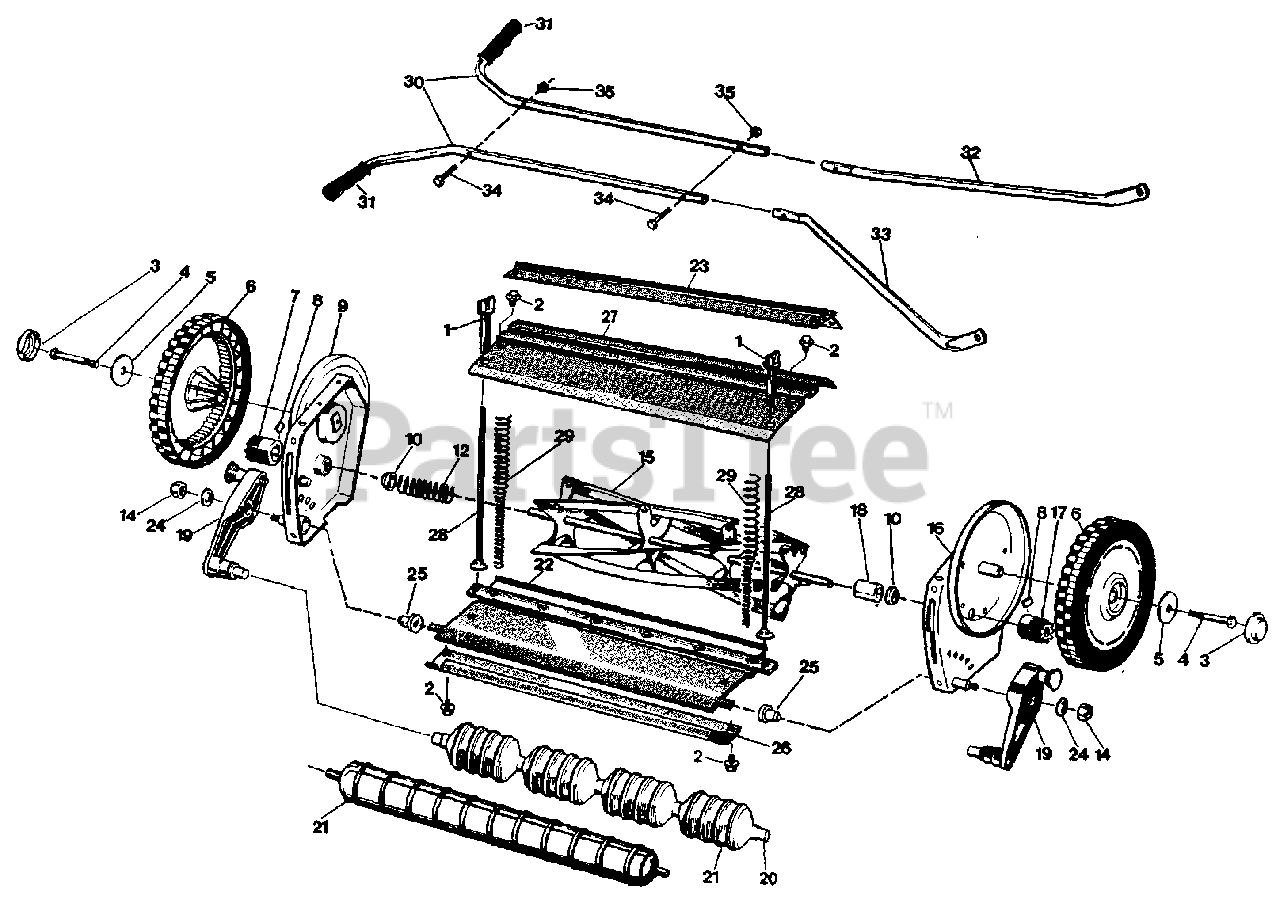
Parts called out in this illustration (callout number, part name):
5	WASHER
7	PINION L
10	INNER RACE
17	REPL BY 371 91 47-01
19	ROLLER HOLDERS (2 PCS) NLA
21	ROLLER 5/30 (ORANGE)
30	HANDLEBAR
32	LOWER TUBE L 33
33	LOWER TUBE R 33
34-35	ASSEMBLY SET
35	REPL BY 732 21 16-01
37	SET OF HOOKS NLA
